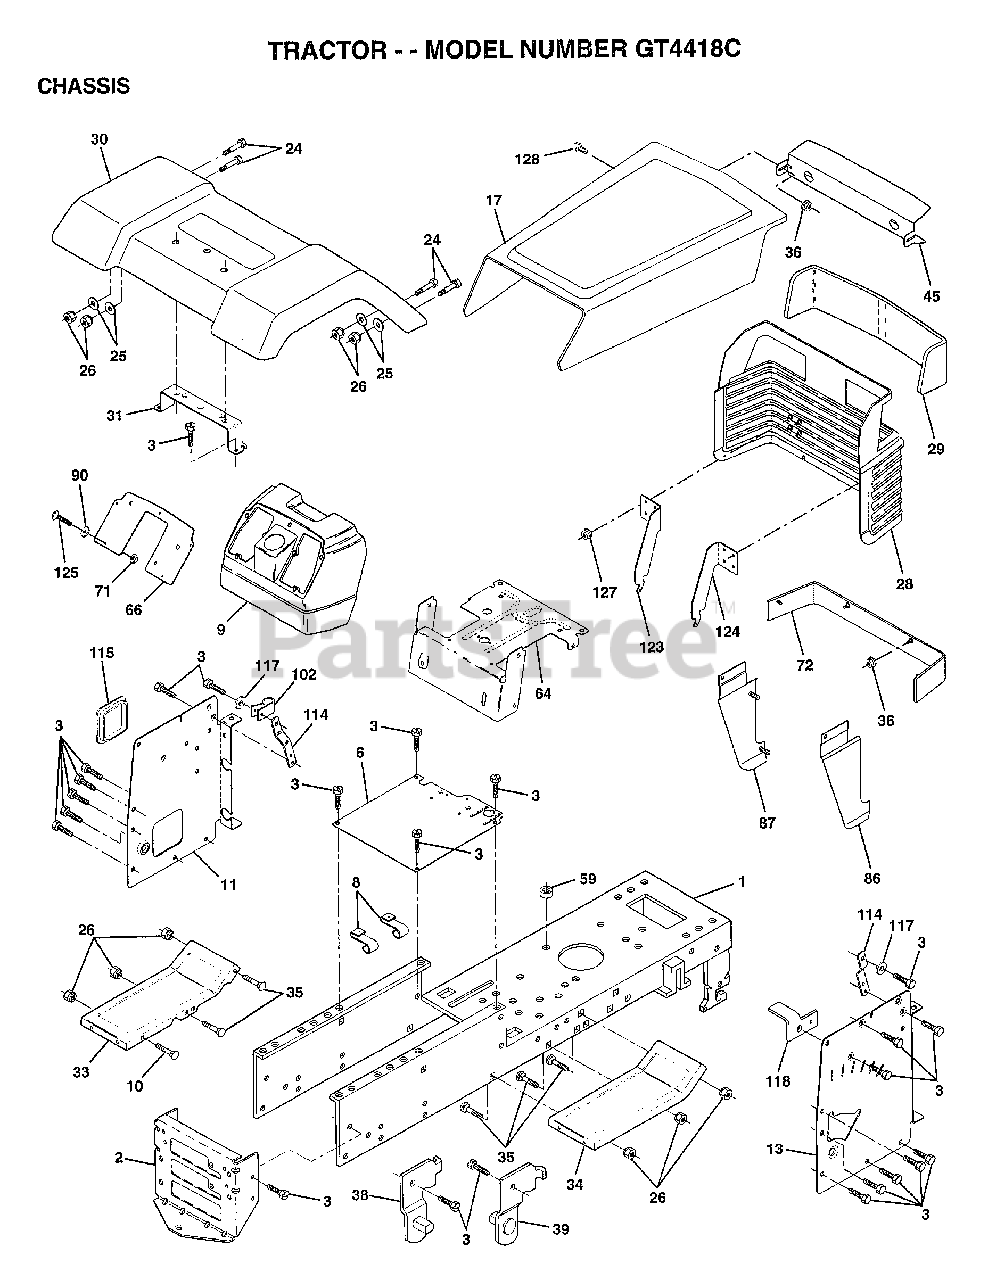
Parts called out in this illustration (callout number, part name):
1	CHASSIS.WLD.11GA
2	DRAW BAR
3	SCREW
8	"CLIP,INSULATOR"
9	DASH.PLASTIC.BLK
11	PANEL.DASH.LH.PNT
13	PANEL.DASH.RH.PNT
14	SCREW LT
17	HOOD/GRILLE ASM
24	BOLT
25	WASHER
26	NUT
28	GRILLE ASM WELD
30	FENDER PNT
31	BRKT.ASM.FENDER
33	FOOTREST.LH.LT/GT
34	FOOTREST.RH.LT/GT
35	BOLT
36	PAL NUT LT
38	BRACKET ASM LH
39	BRACKET ASM RH
44	STRAP ASM FENDER
47	NUT-PUSH YT
65	BOLT
66	PLATE DASH SILKSC
71	NUT HXKEP 1/4X20
72	STRAP FENDER ASM
86	PANEL SIDE RH ASM
87	PANEL SIDE LH ASM
90	WASHER PM
102	CLIP T
114	BRACKET.SUPT.DASH
115	COVER ACCESS
117	WASHER.SERRATED.
118	BRACKET.CLUTCH.MC
123	BRACKET.PICK.RH.
124	BRACKET.PICK.LH.
125	SCREW
127	PAL NUT
128	SCREW SPECIAL
